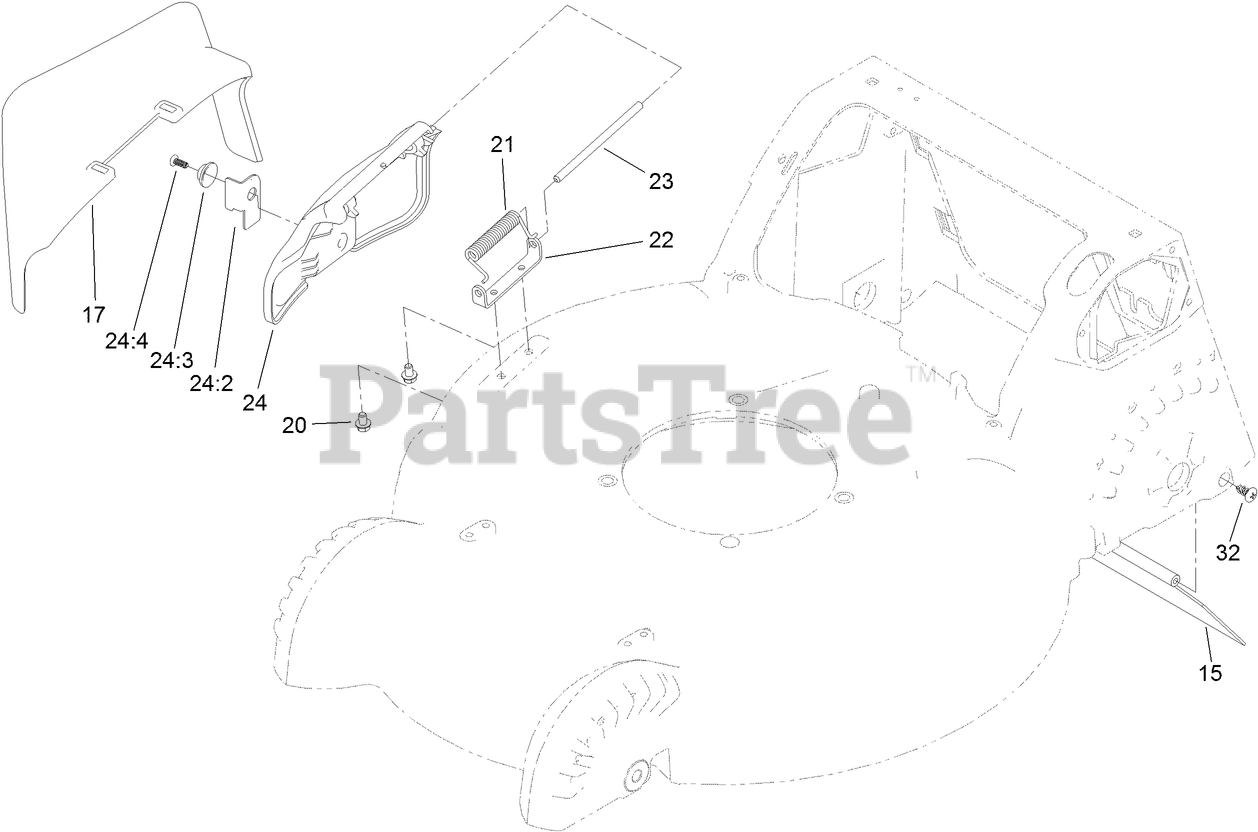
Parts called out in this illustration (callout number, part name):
15	SHIELD-TRAILING
17	CHUTE-DISCHARGE, SIDE
20	SCREW-HWH
21	SPRING-TORSION
22	BRACKET-COVER
23	ROD-COVER
24	DISCHARGE DOOR ASM
24:2	LATCH-DOOR
24:3	CAP-DOOR
24:4	SCREW-PLASTITE
32	SCREW-PTH
